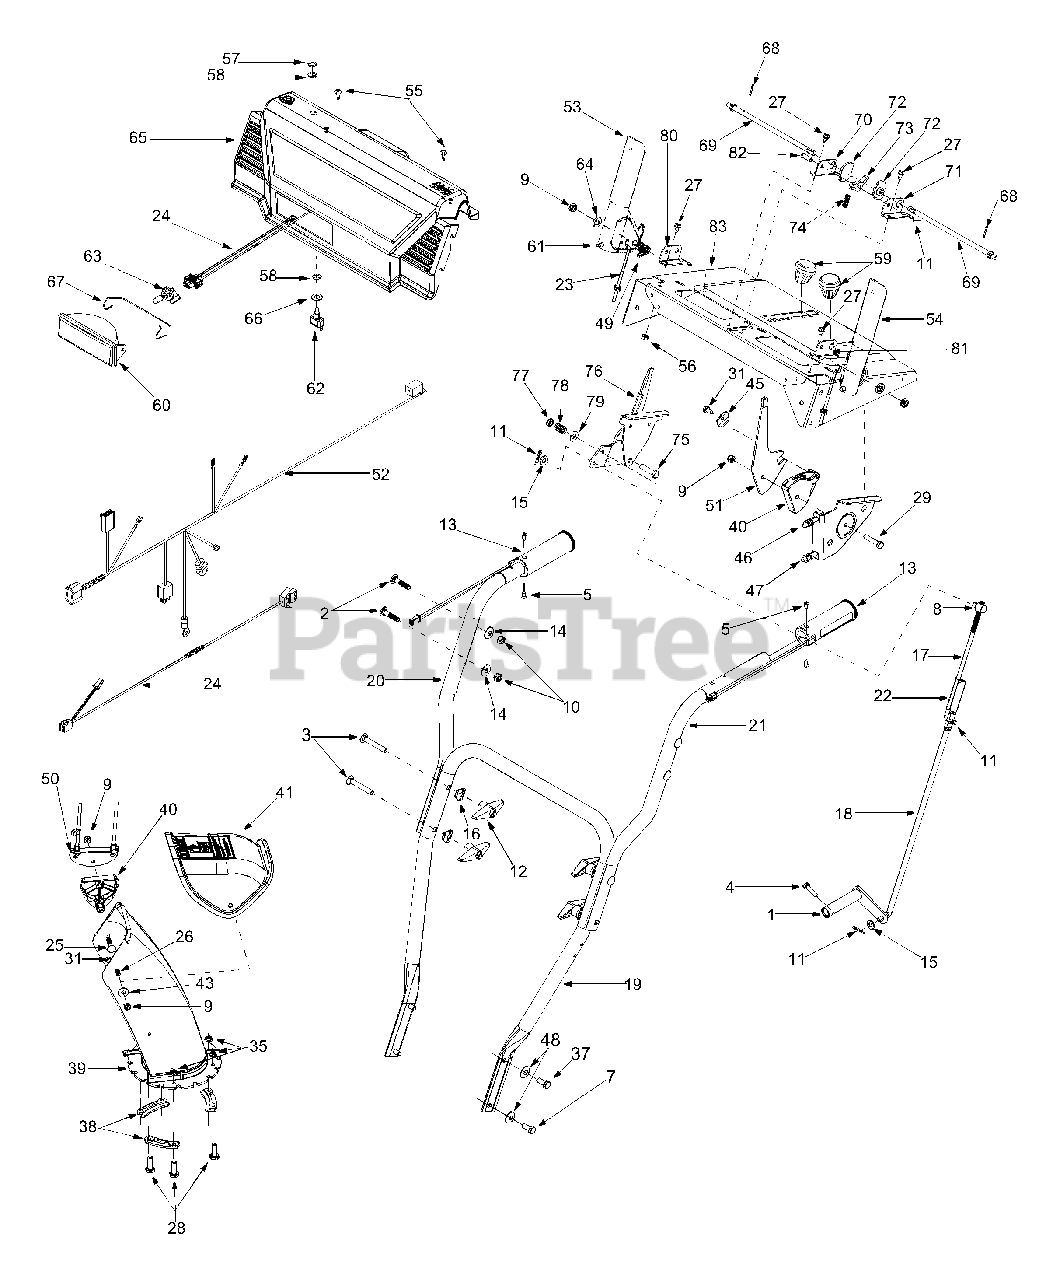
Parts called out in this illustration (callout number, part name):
2	Carriage Bolt 5/16-18 x 1.75"
3	Carriage Bolt 5/16-18 x 2.25"
4	TT Screw 1/4-20 x 1"
5	C-Sunk Screw #10-16x 0.625"
7	Hex Screw 5/16-18 x.75"
8	Ferrule
9	Hex Lock Nut 5/16-18
10	Hex Nut 5/16-18
11	Cotter Pin
12	Handle Knob
13	Heated Grip
14	Belleville Washer
15	Flat Washer
16	Saddle Washer
17	Shift Rod: Upper
18	Shift Rod: Lower
23	Z Cable Fitting
24	Light Harness
25	Carriage Bolt: 5/16-18 x 1.5"
26	Carriage Bolt: 5.16-18 x 1.0"
27	TT Screw: 1/4-20 x 0.5"
28	Hex Screw 1/4-20
29	Hex Screw: 5/16-18 x 1.5"
31	Hex Screw AB:1/4-15 x 0.750"
35	Hex Flange Lock Nut
37	Hex Screw 5/16-18
38	Chute Flange Keeper
39	Lower Chute
40	Cable Guide: Chute Tilt
41	Upper Chute
43	5/16 Washer
45	Special Washer
46	Control Cable
47	Control Cable
48	Lock Washer 5/16
49	Torsion Spring
52	Harness Assembly: Upper
53	Handle Assembly RH
54	Handle Assembly LH
55	Special Hex Screw
56	Hex Sems Nut: 1/4-20
57	Hex Nut
58	Lock Ring: Toggle Switch
59	Shift Knob
60	Lamp Housing
61	Rubber Bumper
62	Toggle Switch: Single Switch
63	Halogen Lamp: 50W, 12V
64	Washer
65	Handle Panel
66	Flat Washer
67	Headlight Retainer
68	Cotter Pin: 3/32 x.75
69	Cam Rod
72	Cam Handle Lock
73	Handle Lock Pawl
74	Compression Spring:.36 x 1.0
75	Hex Cap Screw: 3/8-24 x 1.5
78	Comp. Spring:.39 x.6 x.88
79	Bell Washer
82	Clevis Pin
